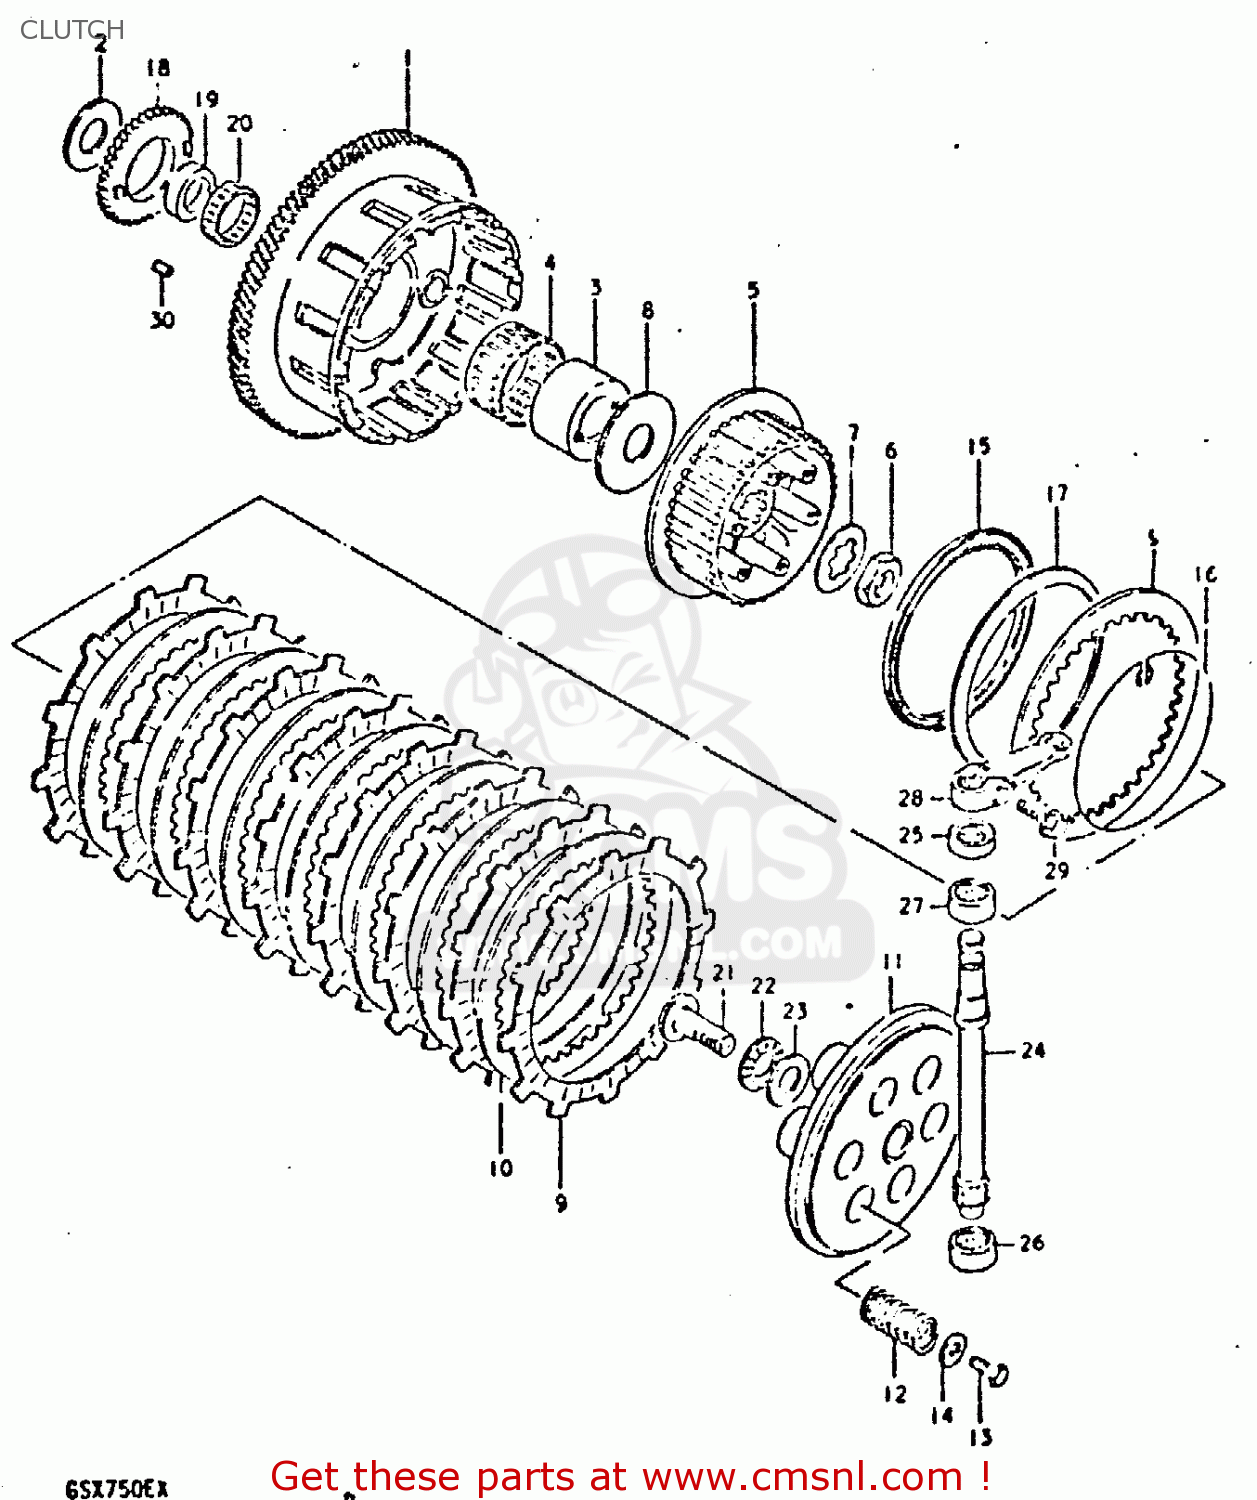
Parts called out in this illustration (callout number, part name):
1	GEAR ASSEMBLY,PRIMARY DRIVE
2	WASHER
3	SPACER,PRIMARY DRIVEN
4	BEARING
5	HUB,CLUTCH SLEEVE
6	NUT
7	WASHER,LOCK
8	WASHER(25X66X3.5)
9	PLATE,CLUTCH DRIVE (MCA)
10	PLATE,CLUTCH DRIVEN(T:2.0) (NAS)
11	DISC,CLUTCH PRESSURE
12	SPRING
13	BOLT, UPPER
14	WASHER
15	SEAT,WAVE WASHER
16	RING,STOPPER
17	WASHER
18	GEAR,ENG OIL PUMP DRIVE(NT:38)
19	SPACER,OIL PUMP DRIVE GEAR
20	BEARING(36X40X10)
21	RACK,CLUTCH RELEASE
22	BEARING(15X28X2)
23	WASHER
24	PINION,CLUTCH RELEASE
25	OIL SEAL
26	BEARING(12X19X12)
27	BEARING(15X22X12)
28	ARM,CLUTCH RELEASE
29	BOLT,REAR
30	CUSHION,PRIMARY DRIVEN GEAR
